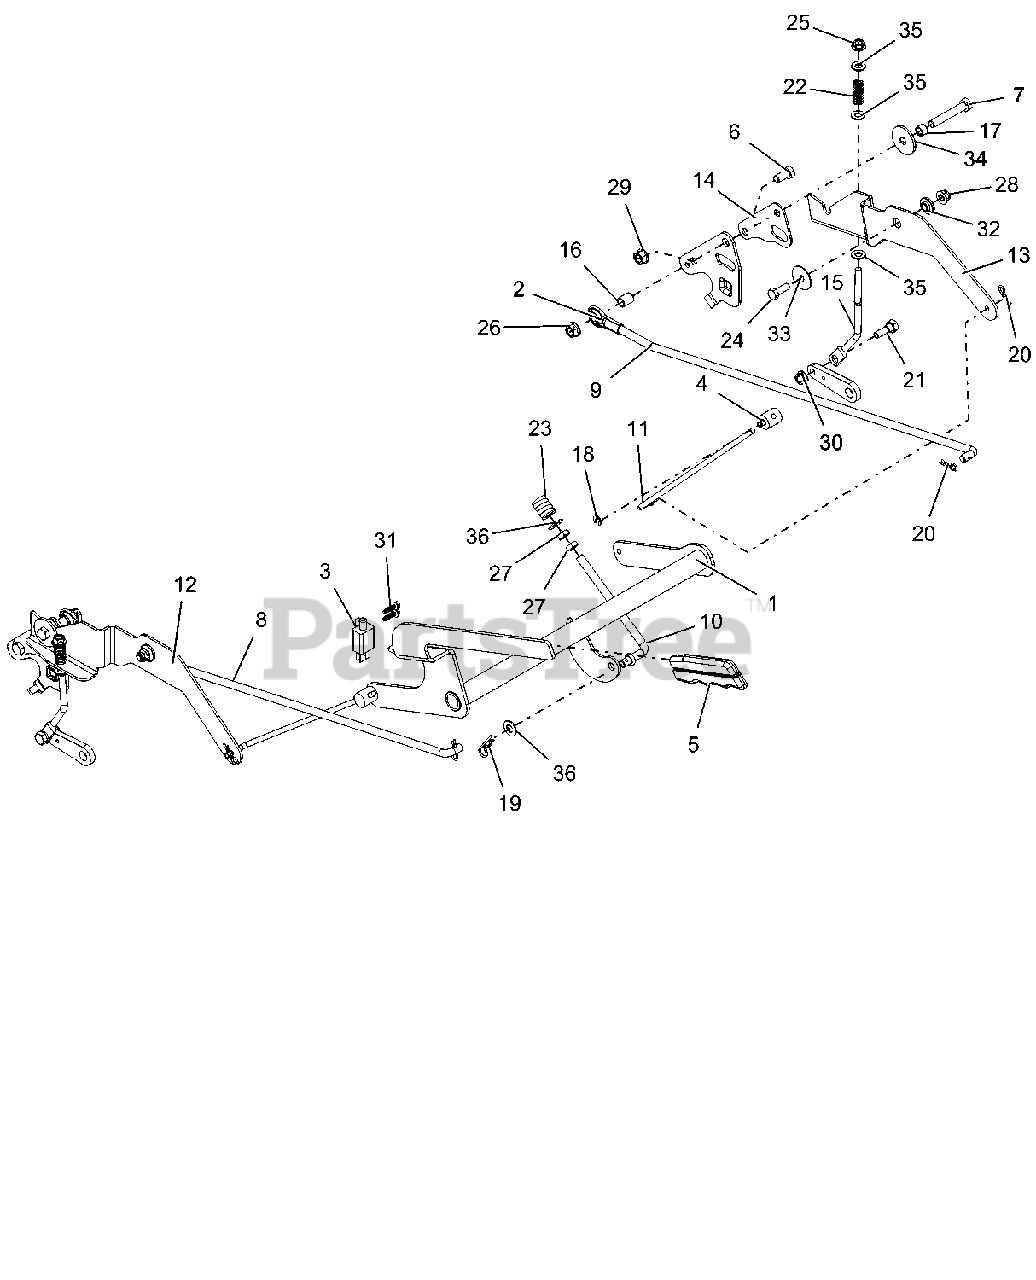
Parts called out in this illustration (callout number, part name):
1	WLDMT, BRAKE LEVER
2	ROD END, .38 RH
3	SWITCH- DOUBLE POLE N.O./N.O.
4	TRUNION, 1/4-20
5	GRIP, PARKING BRAKE (YELLOW)
6	@BLT-HEX .38-16X.75 GR5 YWZC
7	@BLT-HEX .38-16X2.25 GR5 YWZC
8	STEERING, LINKAGE RH
9	STEERING, LINKAGE LH
10	LINK, OVER CENTER, PARKING BRK
11	LINK, BRAKE ARM
12	INTERLOCK, RH BRAKE LINK
13	INTERLOCK, LH BRAKE LINK
14	PLATE, TRANSAXLE ADAPTOR
15	LINK, BRAKE (XL)
16	SPCR, SLV .385X.500X.652
17	SPCR, SLV .385X.500X.350
18	RG-RTNG-EXT .250X.025
19	PIN-HAIR CTR .09 X 1.50 YWZC
20	PIN-HAIR INT .08X.18X1.18 YWZC
21	BOLT,SHLDR .38X.25 -.31-18X.75
22	SPRING, COMPRESSION
23	SG-COMP .187X.56X1.62
24	BOLT-HEX.31-18X.875 YWZC GR5
25	@NUT-LK-CTR-FLG .31-18 YZ GR F
26	NUT-LK-CTR-FLG .38-16 YWZC
27	NUT-HEX-JAM .375-16 YWZC
28	@NUT-LK-NYL-FLG .31-18 YWZC
29	@NUT-LK-TOP-FLG .38-16 YWZC
30	@NUT-LK-TOP-FLG .31-18 YWZC
31	SCR-TAP #12X.75 BOSS INDHXHD
32	BSHG, FLG .325X.499X.26X.88
33	WSHR-FL-STL .347X1.254X.048YWZ
34	WSHR-FL-STL .380X1.50X.125YWZC
35	@WSHR-FL-STL.344X.688X.065YWZC
36	@WSHR-FL-STL.406X.812X.065 YWZ
